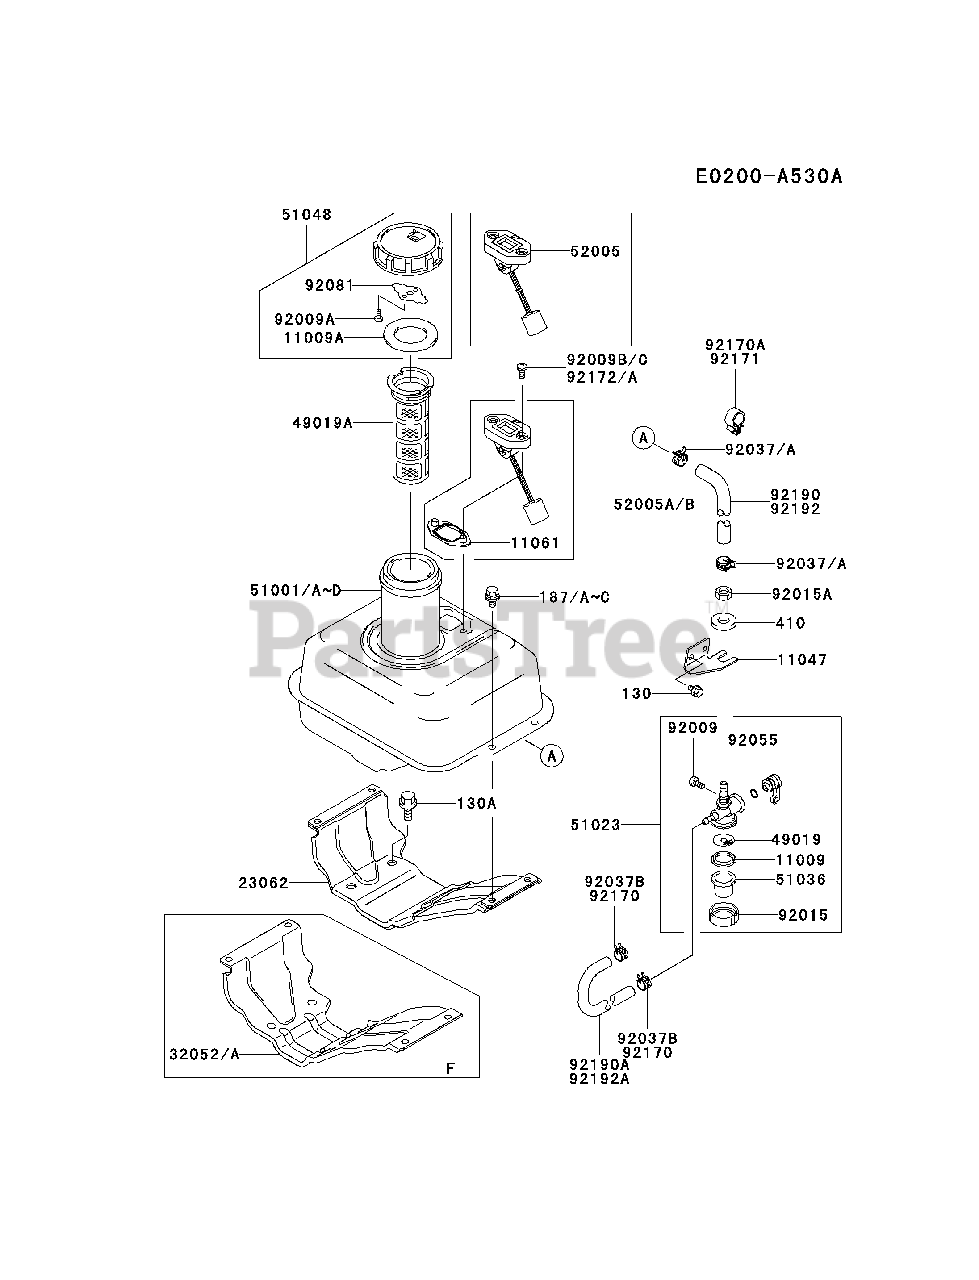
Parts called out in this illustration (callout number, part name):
130	BOLT-FLANGED
130A	BOLT-FLANGED
187A	BOLT-UPSET-WSP
187C	BOLT-UPSET-WSP
410	W-PLAIN-S
